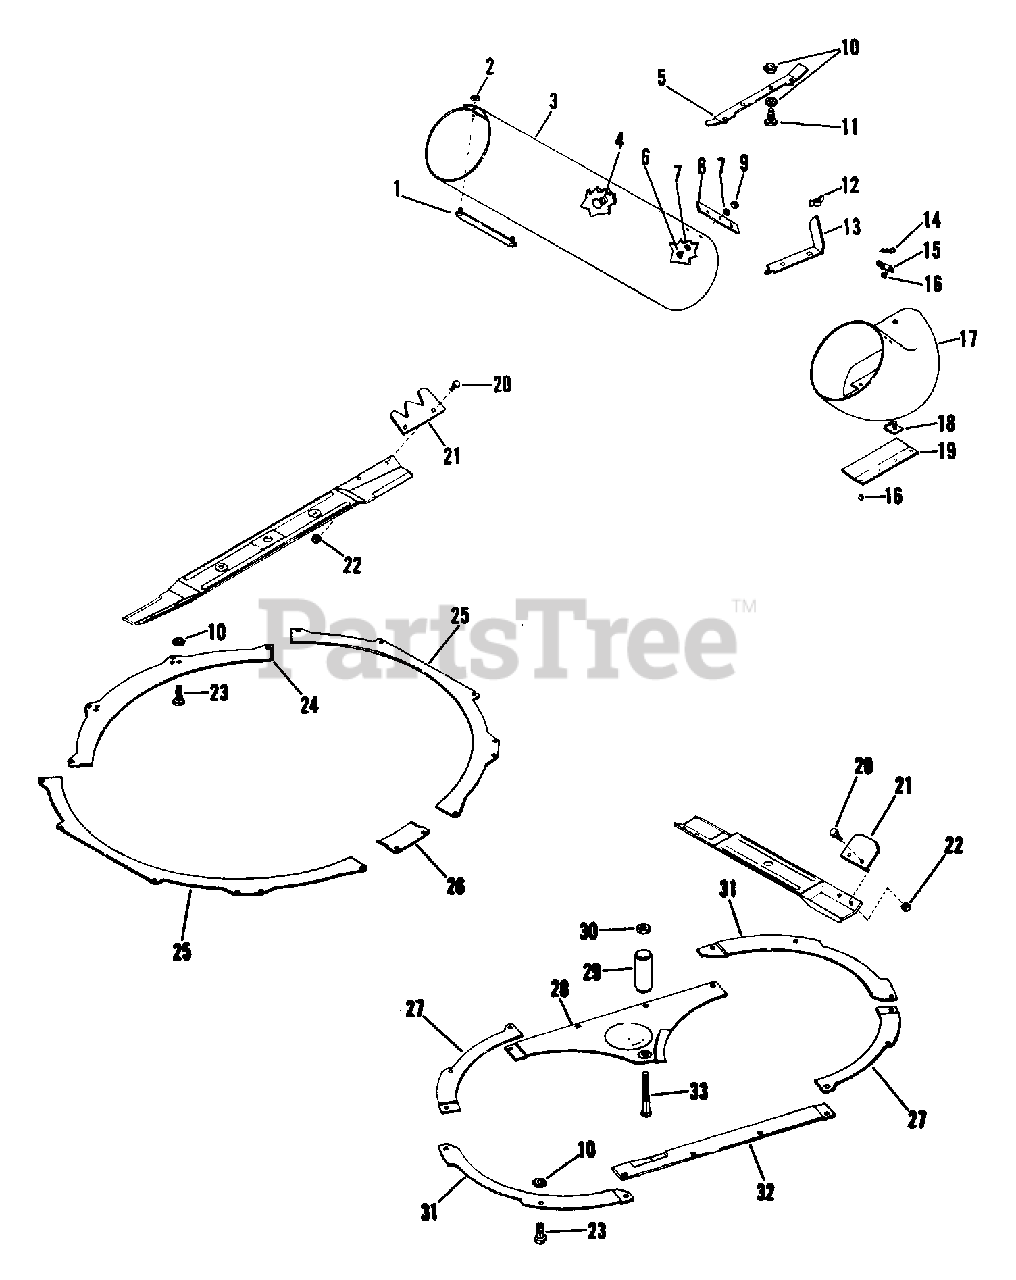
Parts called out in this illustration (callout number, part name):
2	NUT-LK-FLG .250-20 PL
3	TUBE BLANK
4	BLT-RDHDSQNK .25-20X.50 SHT PL
6	SCR-MCH 10-24X.50 SLRH PL
7	WSHR-FL-STL .219X.500X.049 PL
9	NUT-LK TOP 10-24 PL
10	NUT-LK-CTR .250-20 PL
11	BLT-RDHDSQNK .25-20X1.00 GR5
14	PIN-HAIR INT .09X.188 PL
15	RETAINER
16	RVT-TBLR .187X.375 OH ST PL
17	BOOT ASSEMBLY 32"
20	BLT-HEX .31-24X.75 GR8
21	SERVICE VANE PACKAGE
22	NUT-LK TOP .312-24 PL GR C
23	BLT-RDHDSQNK .25-20X.62 PL
24	BACK FLANGE
25	SIDE FLANGE
26	FRONT CLAMP
